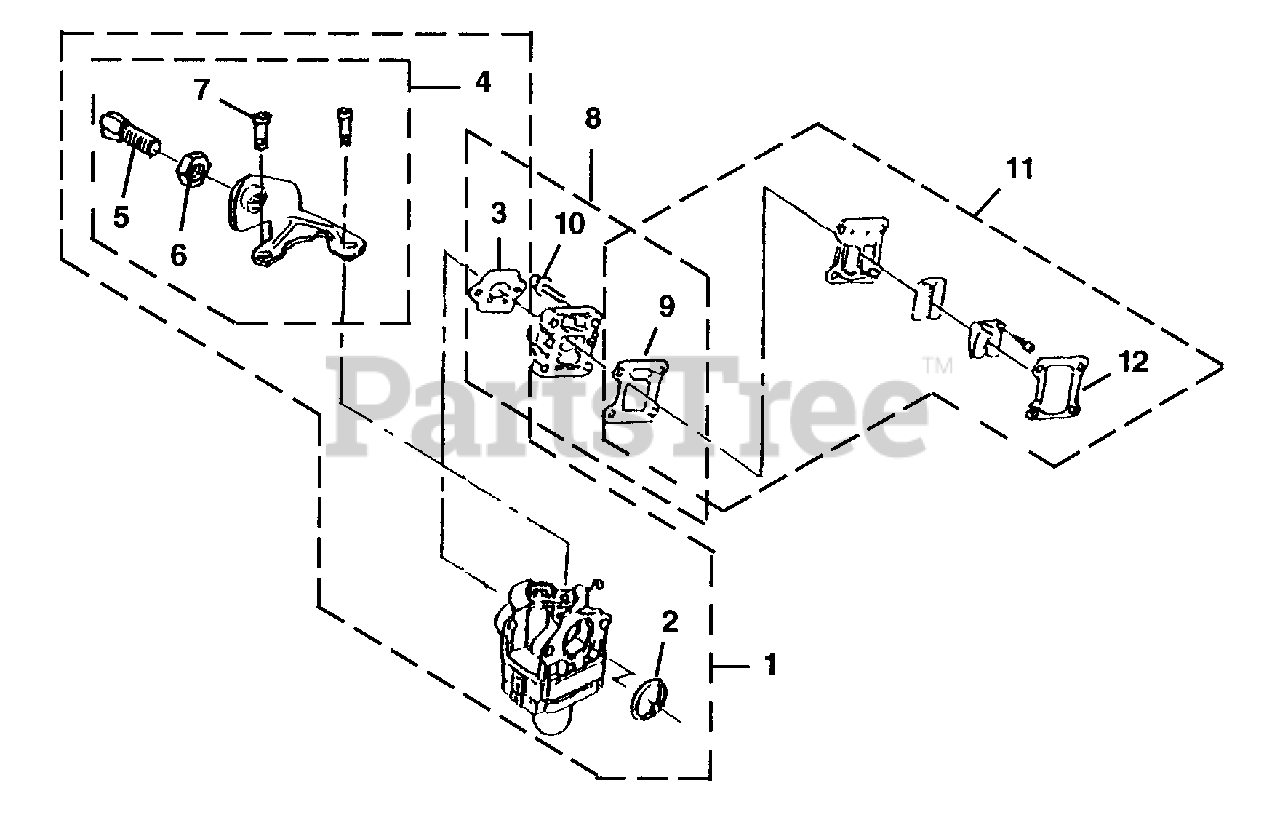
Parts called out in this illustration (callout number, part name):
1	CARBURETOR ASSY
2	RING-Packing
3	GASKET-Carburetor
4	CABLE BRACKET
5	SCREW-Cable Adjust
6	NUT-Cable Adjust
7	SCREW-Throttle Collar
8	HEAT DAM ASSEMBLY
9	GASKET-Heat Dam
10	SCREW-Socket Hd (M5 x 20)
11	REED VALVE ASSY
12	GASKET-Reed Valve
